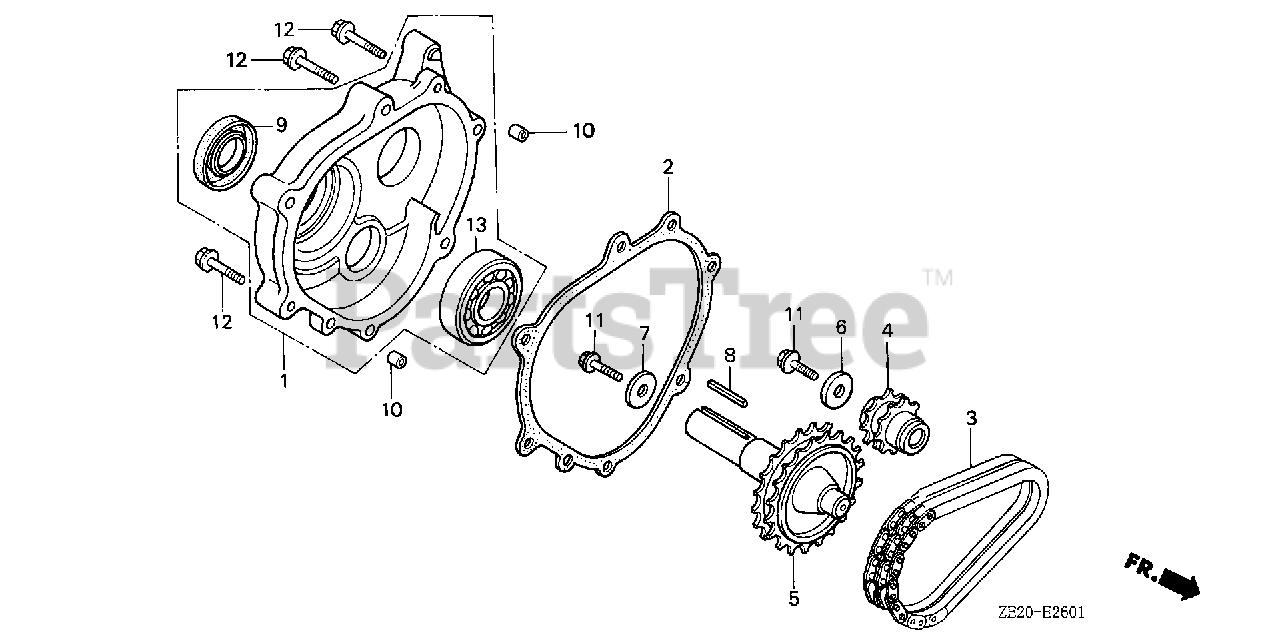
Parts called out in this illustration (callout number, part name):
1	COVER ASSY., CHAIN CASE
2	GASKET, CHAIN CASE COVER
3	CHAIN, P.T.O. DRIVE
4	SPROCKET, DRIVE (14T)
5	SHAFT, P.T.O. (28T)
6	WASHER (8MM)
8	KEY (7X7X33)
8	KEY (7X7X33) (OVER SIZE) (YELLOW)
9	OIL SEAL (30X46X8)
10	PIN, DOWEL (8X12)
10	PIN A, DOWEL (8X12)
11	BOLT, FLANGE (8X25)
12	BOLT, FLANGE (8X40)
13	BEARING, RADIAL BALL (6206)
